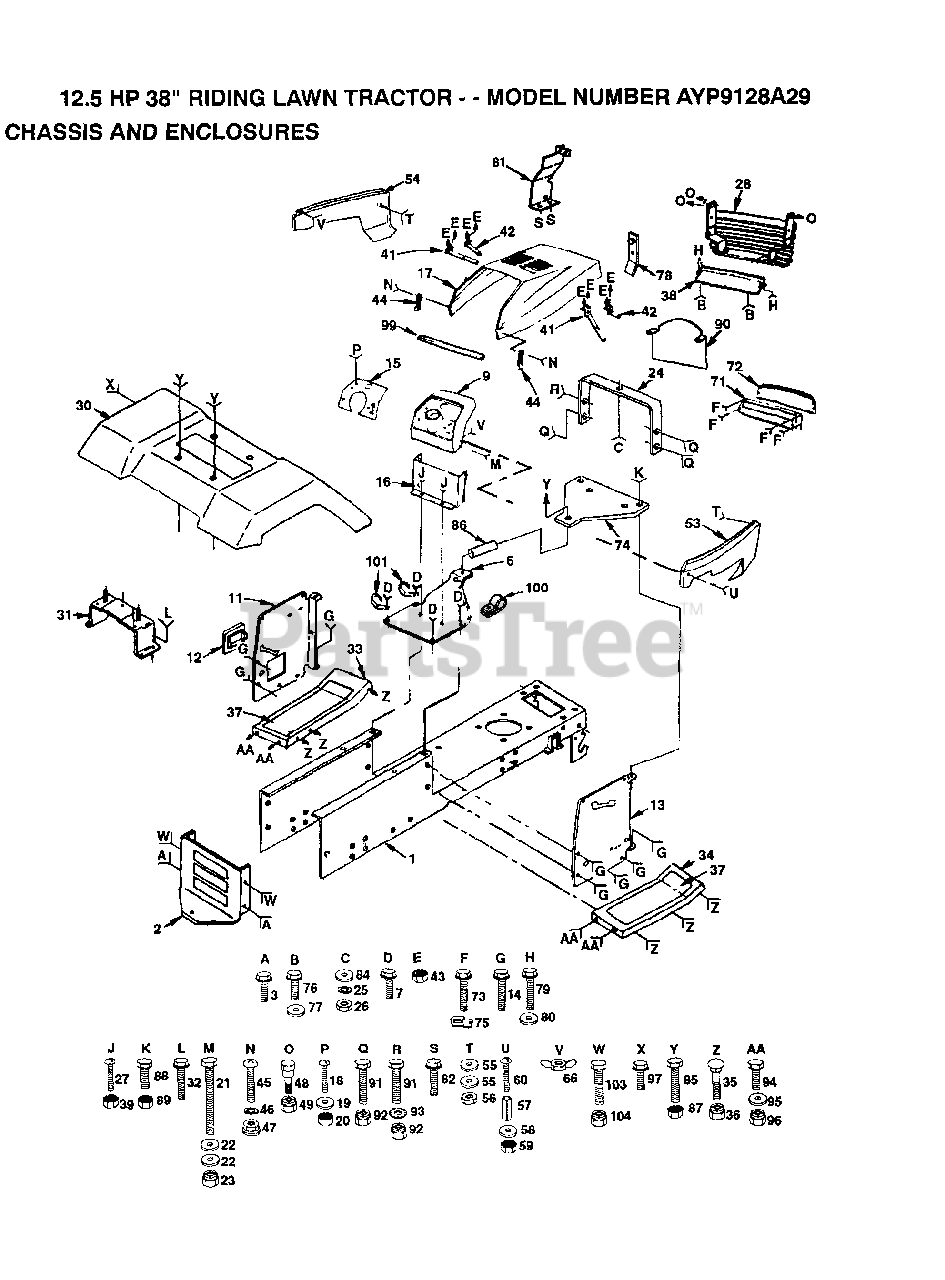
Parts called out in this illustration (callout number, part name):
2	DRAWBAR LT/YT
3	SCREW
7	SCREW LT
11	DASH PANEL LH
12	COVER ACCESS
14	SCREW
18	SCREW
19	WASHER
22	WASHER
24	SUPPORT ASS'Y
25	LOCKWASHER
27	SCREW
32	SCREW
35	BOLT
37	"PAD,FOOTREST"
43	NUT
44	HOOD LATCH T
45	SCREW
46	LOCKWASHER
47	WELDNUT
55	WASHER PM
57	SPACER LT
58	WASHER
60	SCREW
72	LENS LT
74	PLATE SUPPORT BATTERY
75	"""J"" FASTENER LT"
76	SCREW
77	WASHER
79	SCREW HEX CRT
80	WASHER
82	SCREW
84	WASHER PM
85	BOLT
86	SPACER
89	NUT
90	BAFFLE HOOD VERT
95	WASHER
97	SCREW LT
100	CLIP T
101	"CLIP,INSULATOR"
